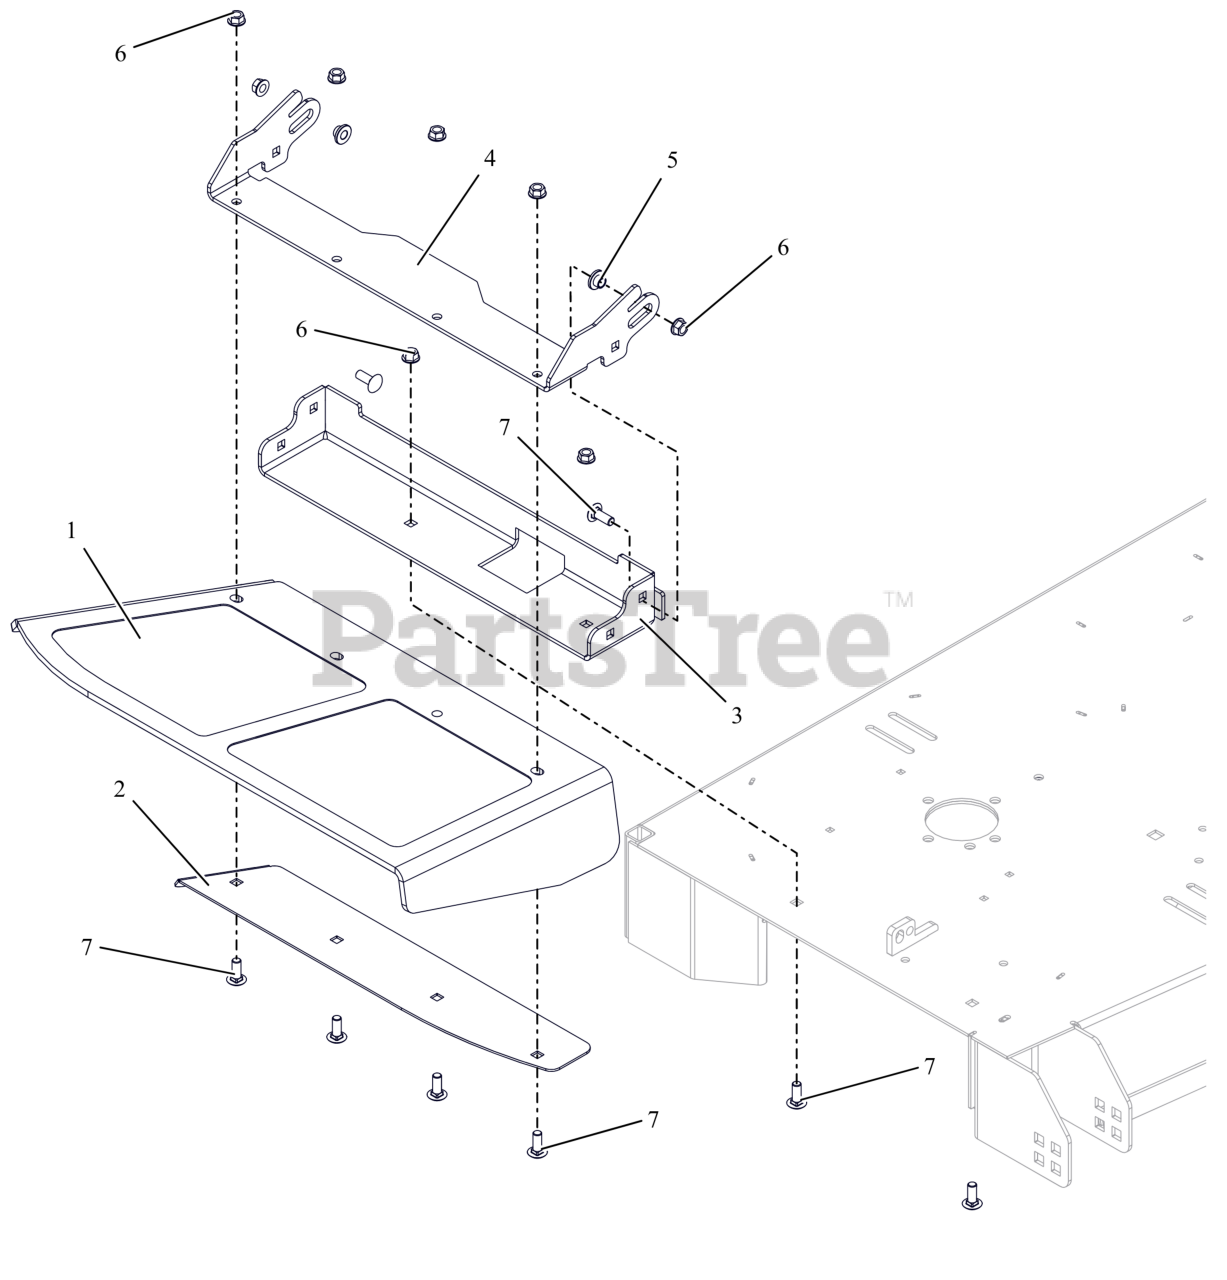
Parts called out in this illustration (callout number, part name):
1	CHUTE, 72" FORMED RUBBER DISCH
2	DISCH CHUTE CLAMP PLT -BLK
3	BASE- DISCHARGE CHUTE MTG
4	BRKT- CHUTE MTG
5	BSHG-FLG .385X.500X.875X.406
6	NUT-LK-CTR-FLG .375-16 GF ZCC
7	BLT,RHSSN .38-16X1.00 G5 ZCC
